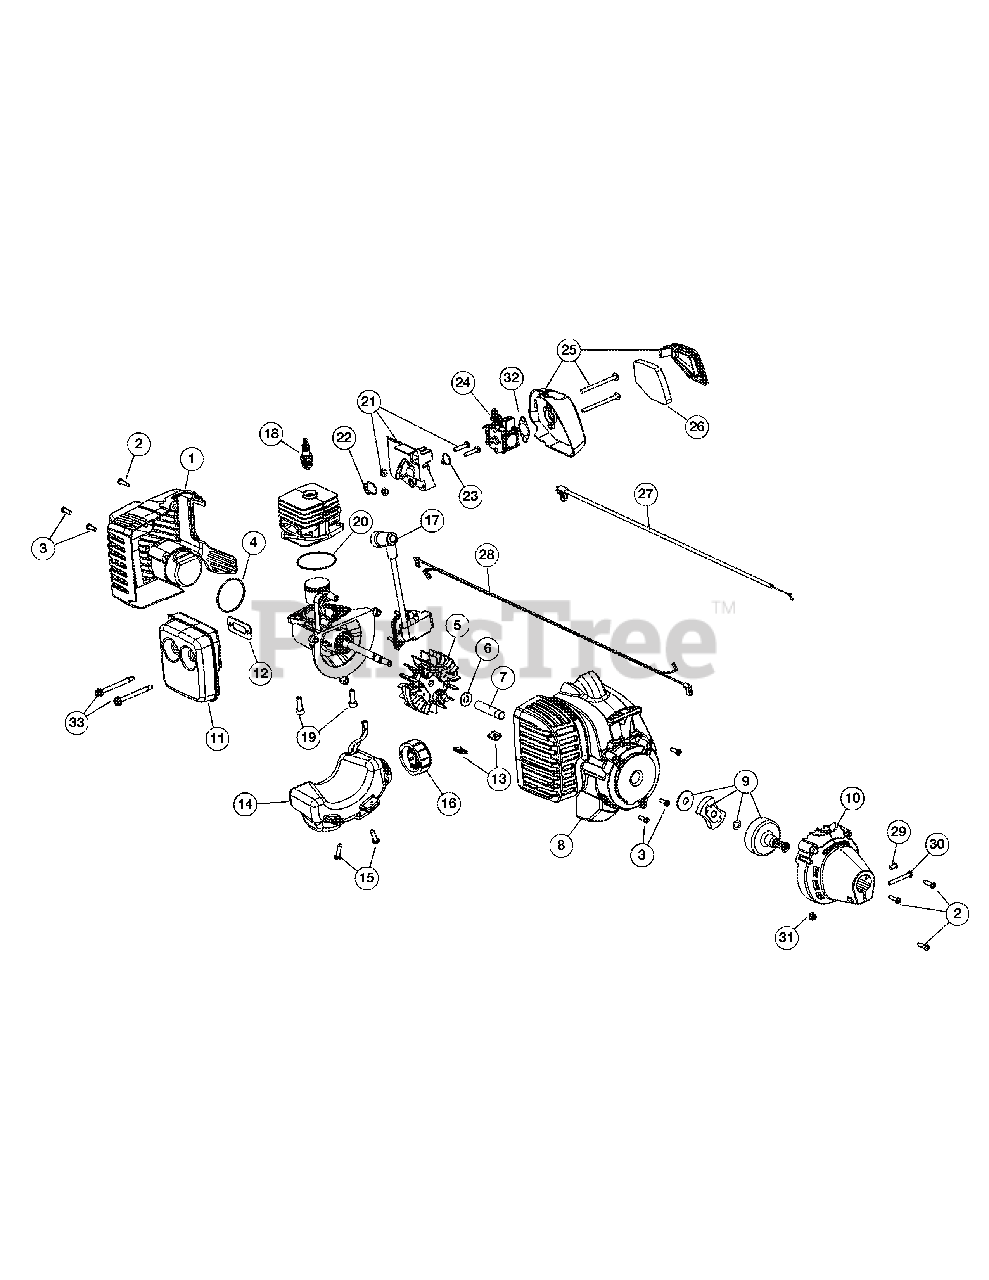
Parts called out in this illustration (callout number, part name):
1	Rear Cover Assembly (Incl. Ref No.2 & 3)
2	Cover Screw
3	Housing Screw
4	O-Ring
5	Flywheel Assembly
6	Washer
7	Spacer
8	Starter Housing (Incl. Ref No.3 & 13)
9	Starter Clutch Assembly
10	Clutch Cover (Incl. Ref No.2)
11	Muffler Assembly (Incl. Ref No.12 & 33)
12	Muffler Gasket
13	U-shaped Nut
14	Fuel Tank Assembly (Incl. Ref No.15 & 16)
15	Tank Screw
16	Fuel Cap
17	Module Assembly
18	Spark Plug
19	Crankcase Bolt
20	Crankcase O-Ring
21	Insulator Assembly (Incl. Ref No.22 & 23)
22	Insulator O-Ring
23	Carburetor O-Ring
24	Carburetor
25	Aircleaner Cover Assembly (Incl. Ref No.26)
26	Aircleaner Filter
27	Throttle Cable
28	Lead Wires
29	Anti-rotation Screw
30	Clamp Screw
31	Clamp Nut
32	Air Cleaner Gasket
33	Muffle Screws
